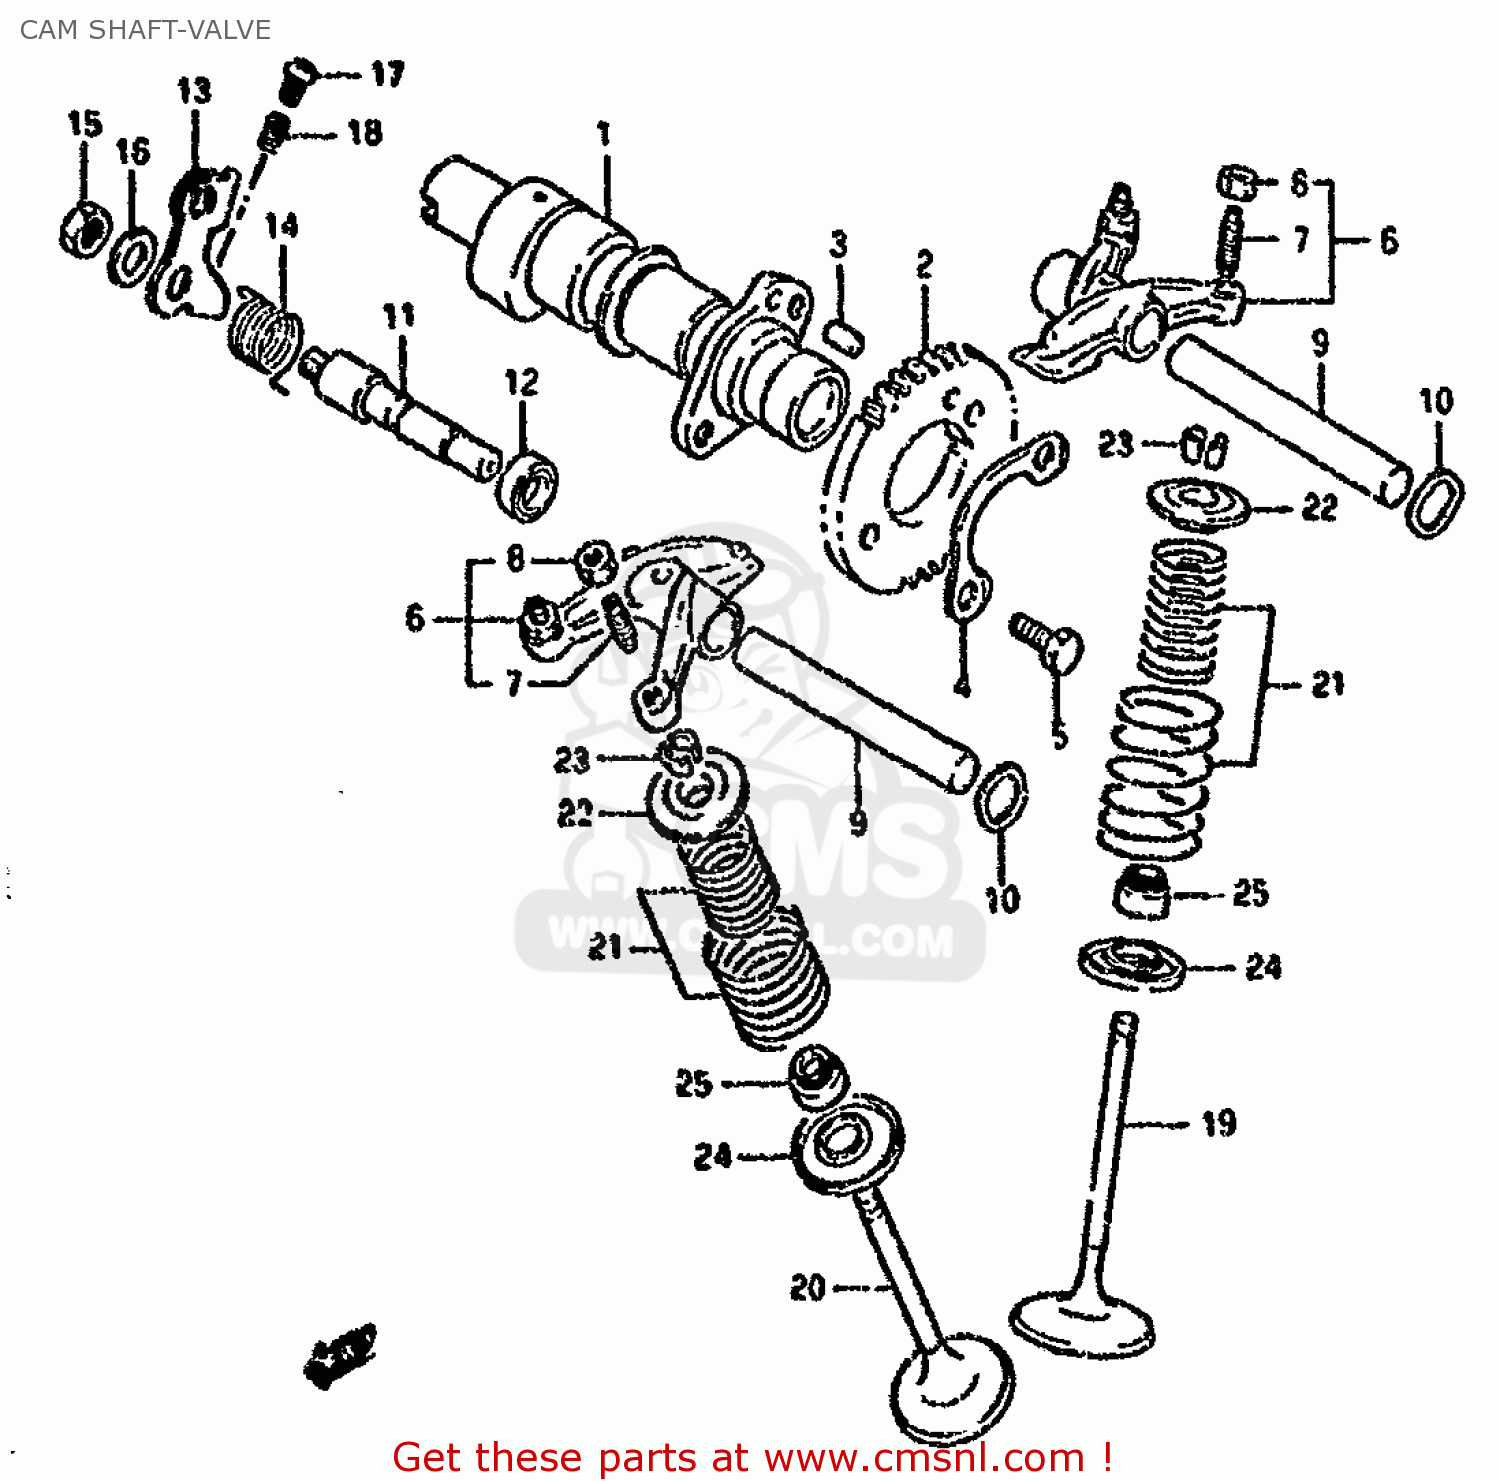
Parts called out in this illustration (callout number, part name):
1	CAMSHAFT
2	SPROCKET,CAMSHAFT
3	PIN
4	WASHER,SPROCKET
5	BOLT(6X14)
6	ARM,VALVE ROCKER
7	SCREW,TAPPET ADJUSTING
8	NUT,ADJUSTING SCREW
9	SHAFT,VALVE ROCKER ARM
10	WASHER
11	SHAFT,DECOMP.
12	SEAL,OIL(10X17X6)
13	LEVER, DECOMP SHAFT
14	SPRING
15	NUT
16	WASHER
17	SCREW
18	SPRING
19	VALVE,INTAKE
20	VALVE,EXHAUST
21	SPRING SET,VALVE
22	RETAINER,VALVE SPRING
23	COTTER,VALVE
24	SEAT,VALVE SPRING
25	SEAL,OIL(7X14.4X9)
